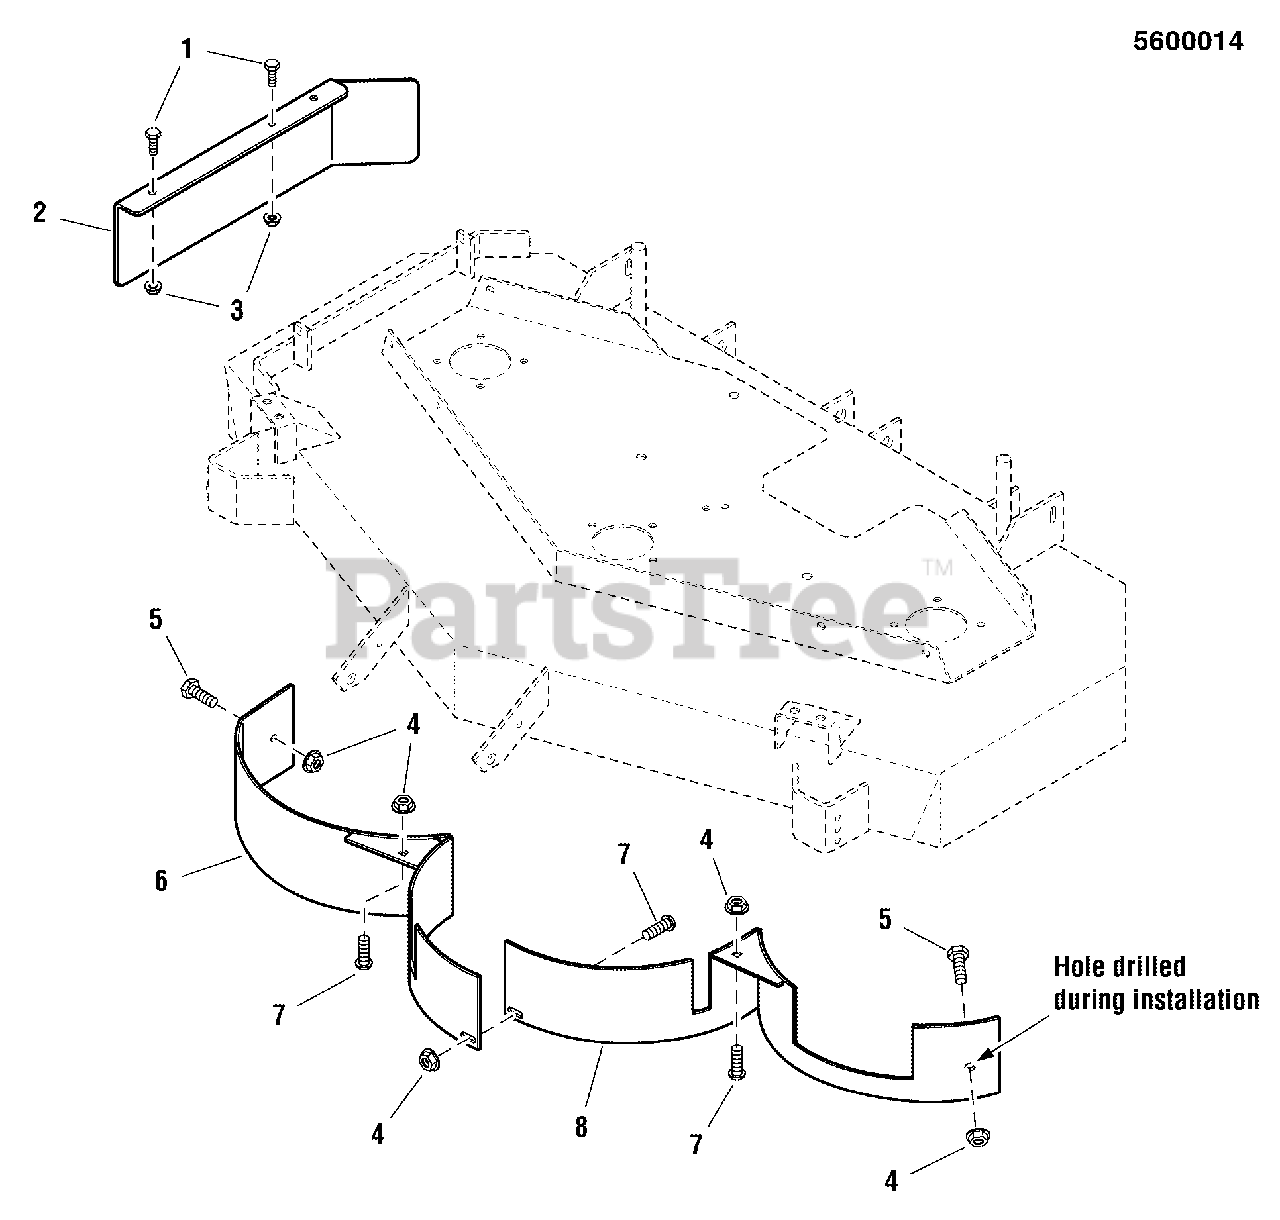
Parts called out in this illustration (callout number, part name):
1	BOLT, 1/4-20 X 3/4, GD5
2	PLATE, Blockoff
3	NUT, Nylock Flanged, 1/4-20
4	NUT, Hex Nylock Flange, 5/16-18
5	BOLT, 5/16-18 X 3/4 GD5
6	PLATE, Mulching, LH
7	BOLT, Carriage, 5/16-18 X 1
8	PLATE, Mulching, RH
